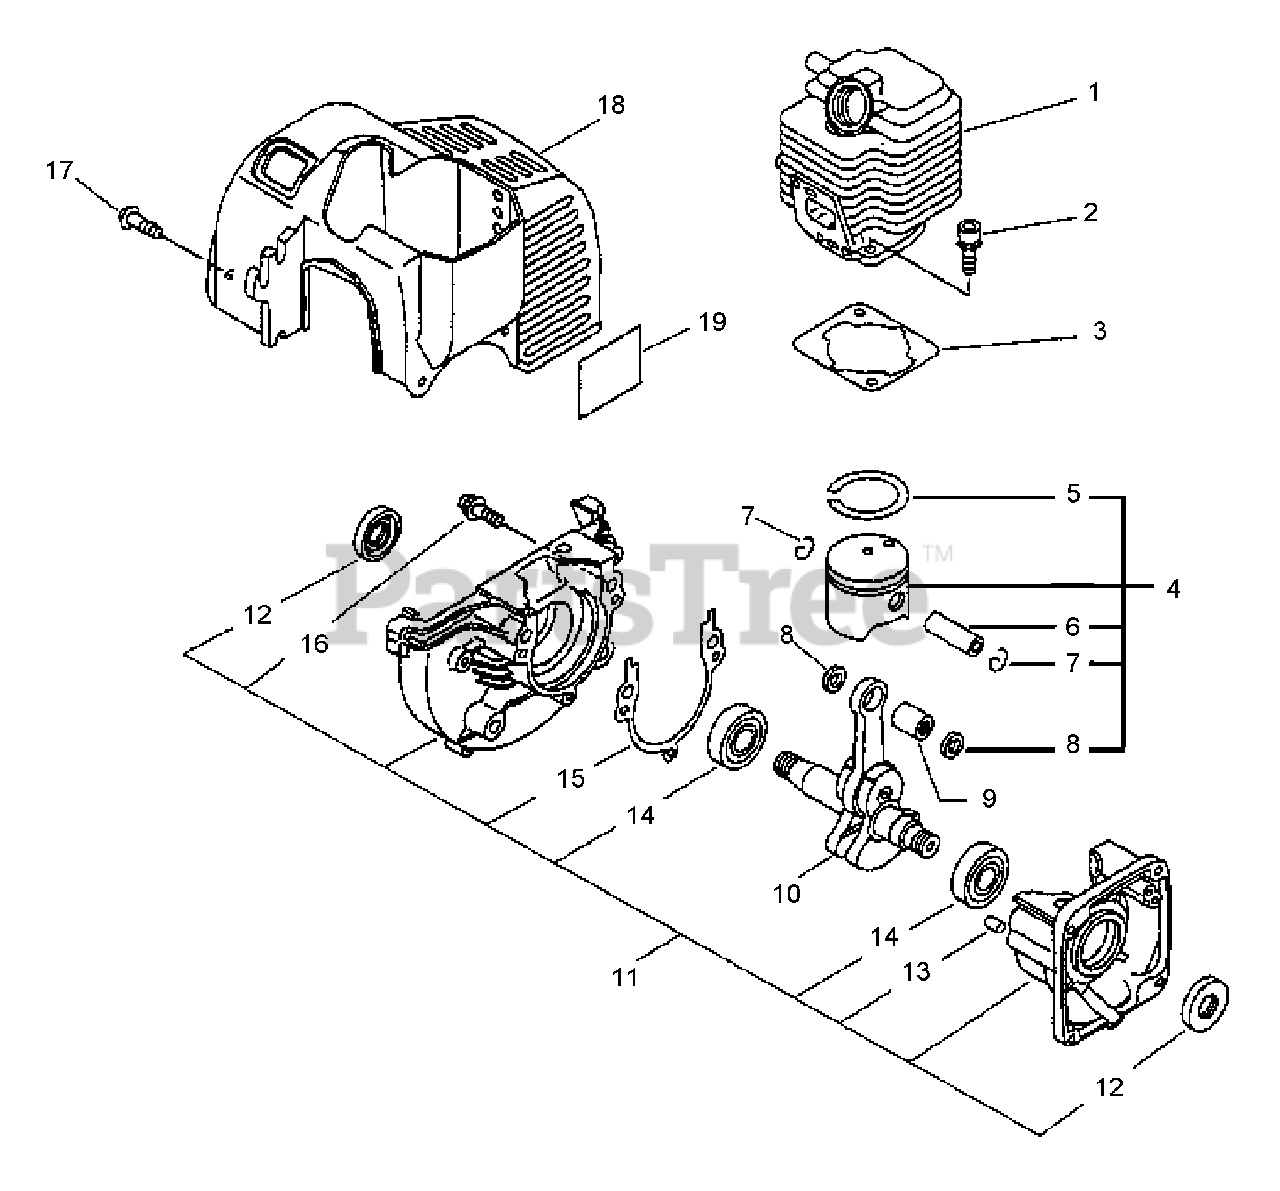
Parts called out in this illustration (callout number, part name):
2	BOLT 5×22
3	GASKET, CYLINDER
4	PISTON KIT
5	RING, PISTON
6	PIN, PISTON 8
7	RING, SNAP
8	WASHER, THRUST
9	BEARING, NEEDLE
10	CRANKSHAFT
11	CRANKCASE KIT
12	SEAL, OIL 12
13	PIN, LOCATING 4
14	BEARING, BALL - 6201 C3
15	GASKET, CRANKCASE
16	BOLT 5×28
17	SCREW 4×16
18	COVER, ENGINE - ORANGE
18	COVER, ENGINE - GRAY
19	LABEL, MODEL
